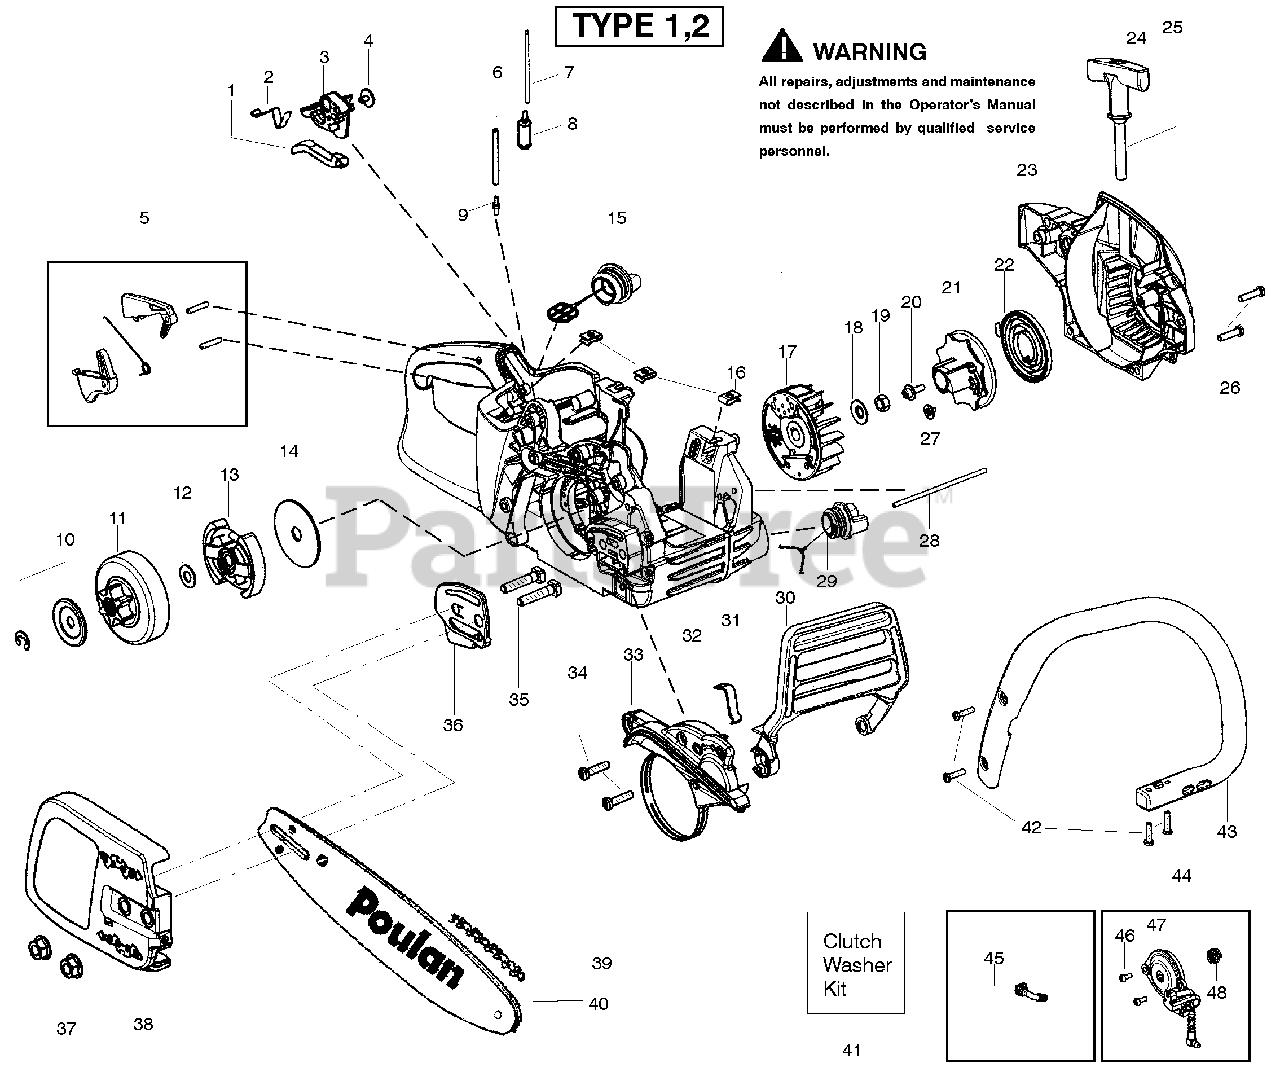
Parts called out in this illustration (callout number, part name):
1	Knob-Choke
2	Spring-Ign. Switch
3	Lever-Ign. Switch
5	Kit-Trigger/Lockout
6	Kit-Fuel Line (Large)
7	Kit-Fuel Line (Small)
8	Assy-Fuel Pick Up
9	Fitting-Fuel line
10	Kit-Clutch Washer
11	Assy-Clutch Drum 3/8"
12	Kit-Clutch Washer
13	Assy-Clutch
14	Washer-Large Clutch
15	Assy-Fuel Cap w/ret
16	Nut-"U" type speed
17	Assy.-Flywheel
18	Washer-Flywheel
19	Nut-Flywheel
21	Pulley-Starter
22	Spring-Starter
23	Housing-Fan
24	Handle-Starter
25	Kit-Rope
28	Assy-Oil Vent
29	Assy-Oil Cap w/ret.
30	Handguard
31	Spring-Handguard
32	Assy-Chassis
33	Kit-Chainbrake
35	Bolt-Bar
36	Plate-Bar
38	Clutch Cover
39	Accy-16" Chain
40	Bar -16"
41	Kit-Clutch Washer
43	Handle-Front
44	Kit-Oil Pump
45	Assy-Oil Pick Up
47	Assy-Oil Pump
48	Gear-Worm
